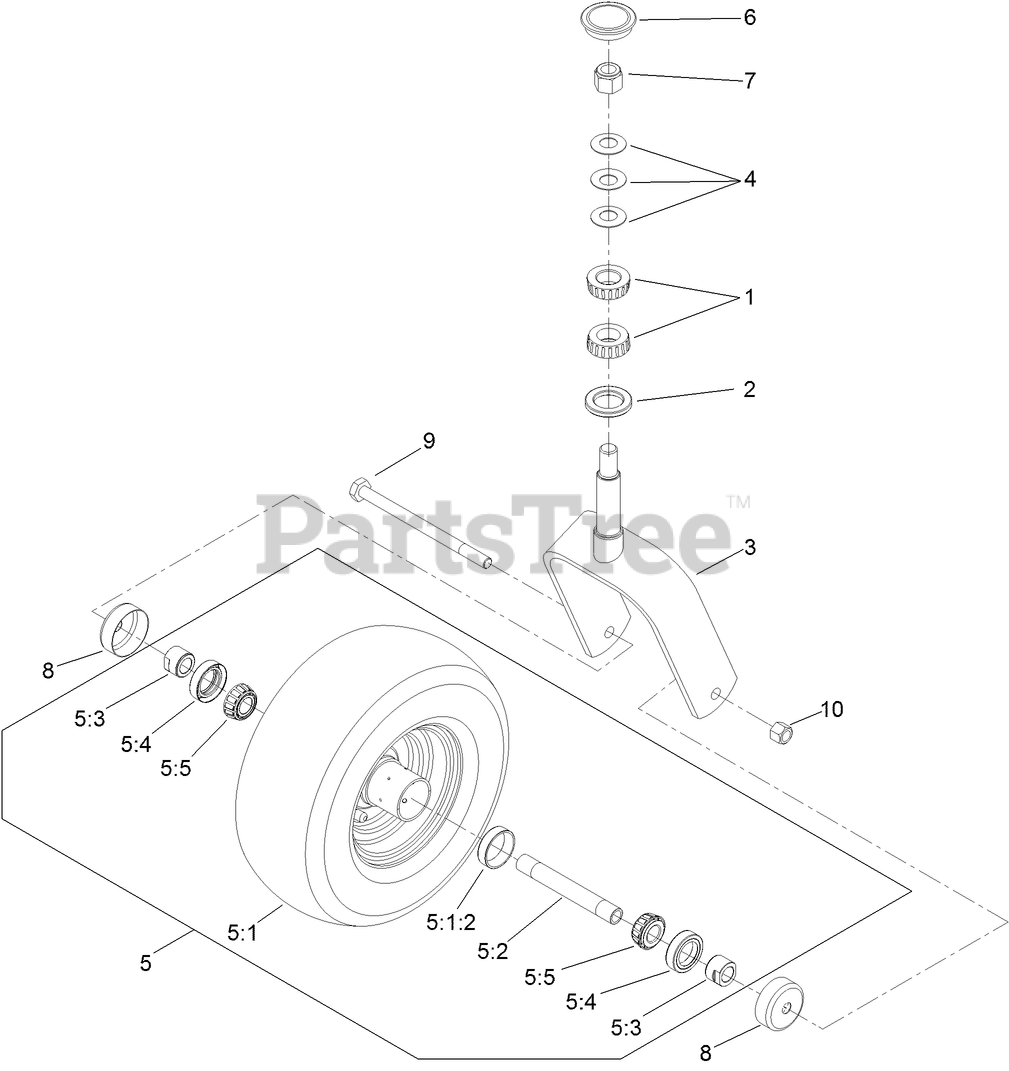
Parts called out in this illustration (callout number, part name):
1	BEARING-ROLLER, TAPERED
2	SEAL-GREASE
3	FORK-CASTER
4	WASHER-BELLVILLE
5	WHEEL AND BEARING ASM
5:1	WHEEL AND TIRE ASM
5:1:2	BEARING-CUP
5:2	AXLE-CASTER
5:3	SPACER-NUT
5:4	SEAL-CASTER
5:5	BEARING-CONE, TAPER
6	CAP-GREASE
7	NUT-LOCK, NI
8	GUARD-SEAL
9	SCREW-HH
10	NUT-LOCK, NI
